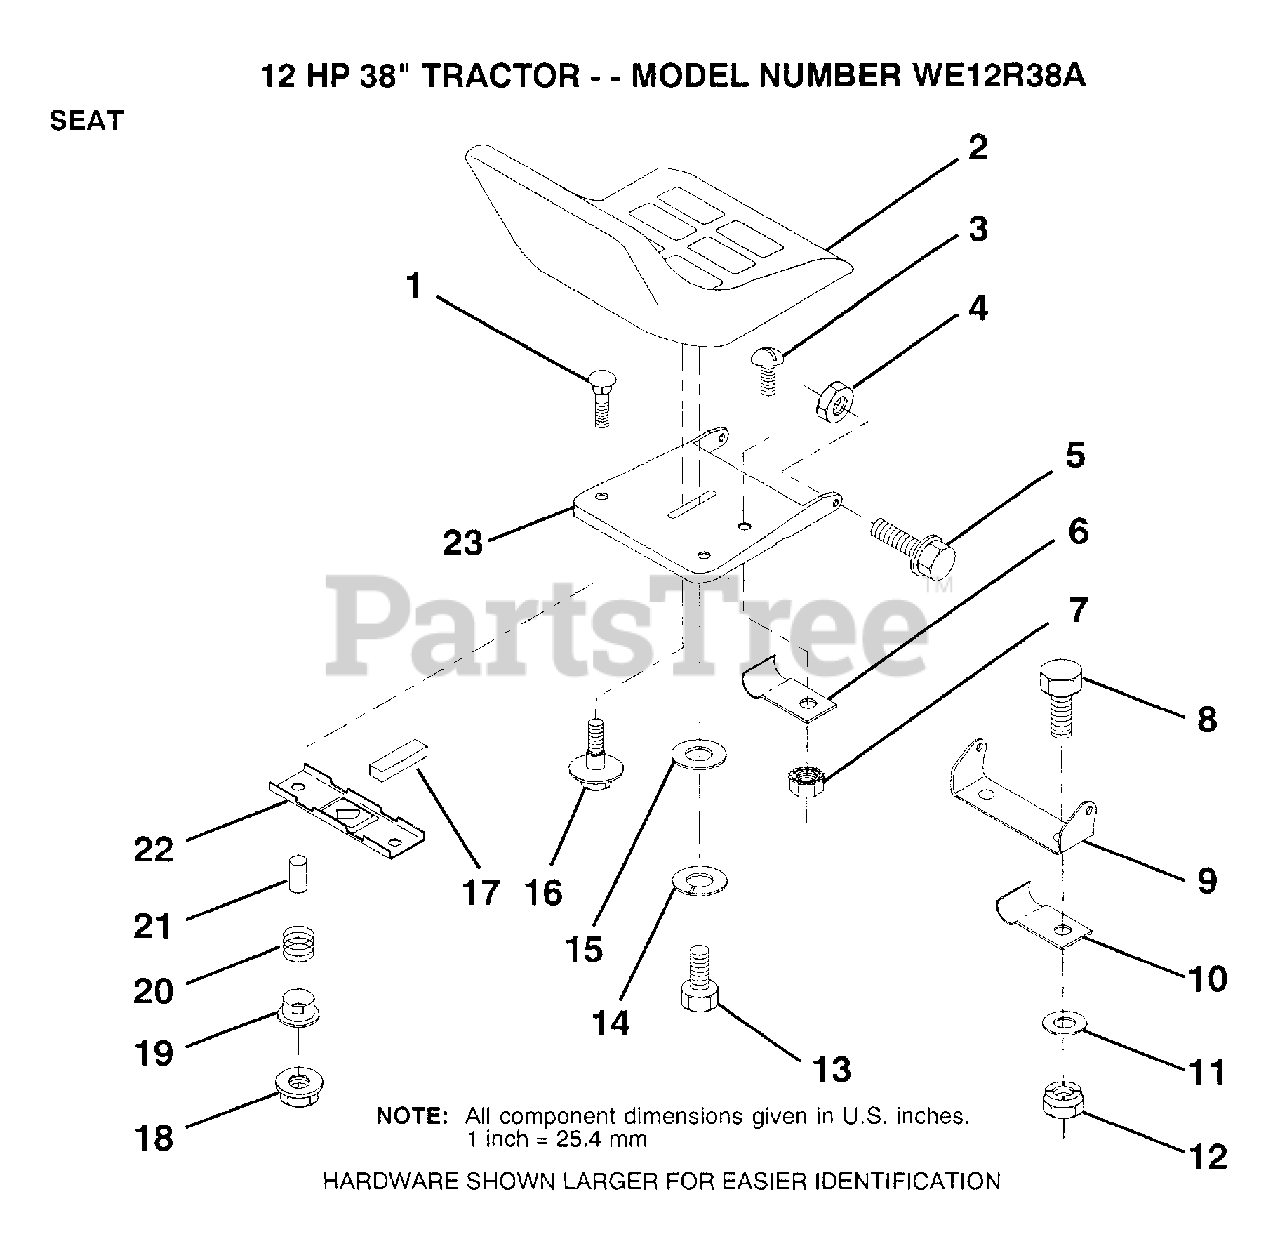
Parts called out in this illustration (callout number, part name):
7	"NUT,KEPS"
10	"CLIP,INSULATOR"
11	WASHER
13	BOLT
14	LOCKWASHER
15	WASHER
16	"BOLT,SHOULDER"
17	STRIP FORM
19	BUSHING
20	SPRING
21	SPLIT SPACER
22	BRKT SWITCH
